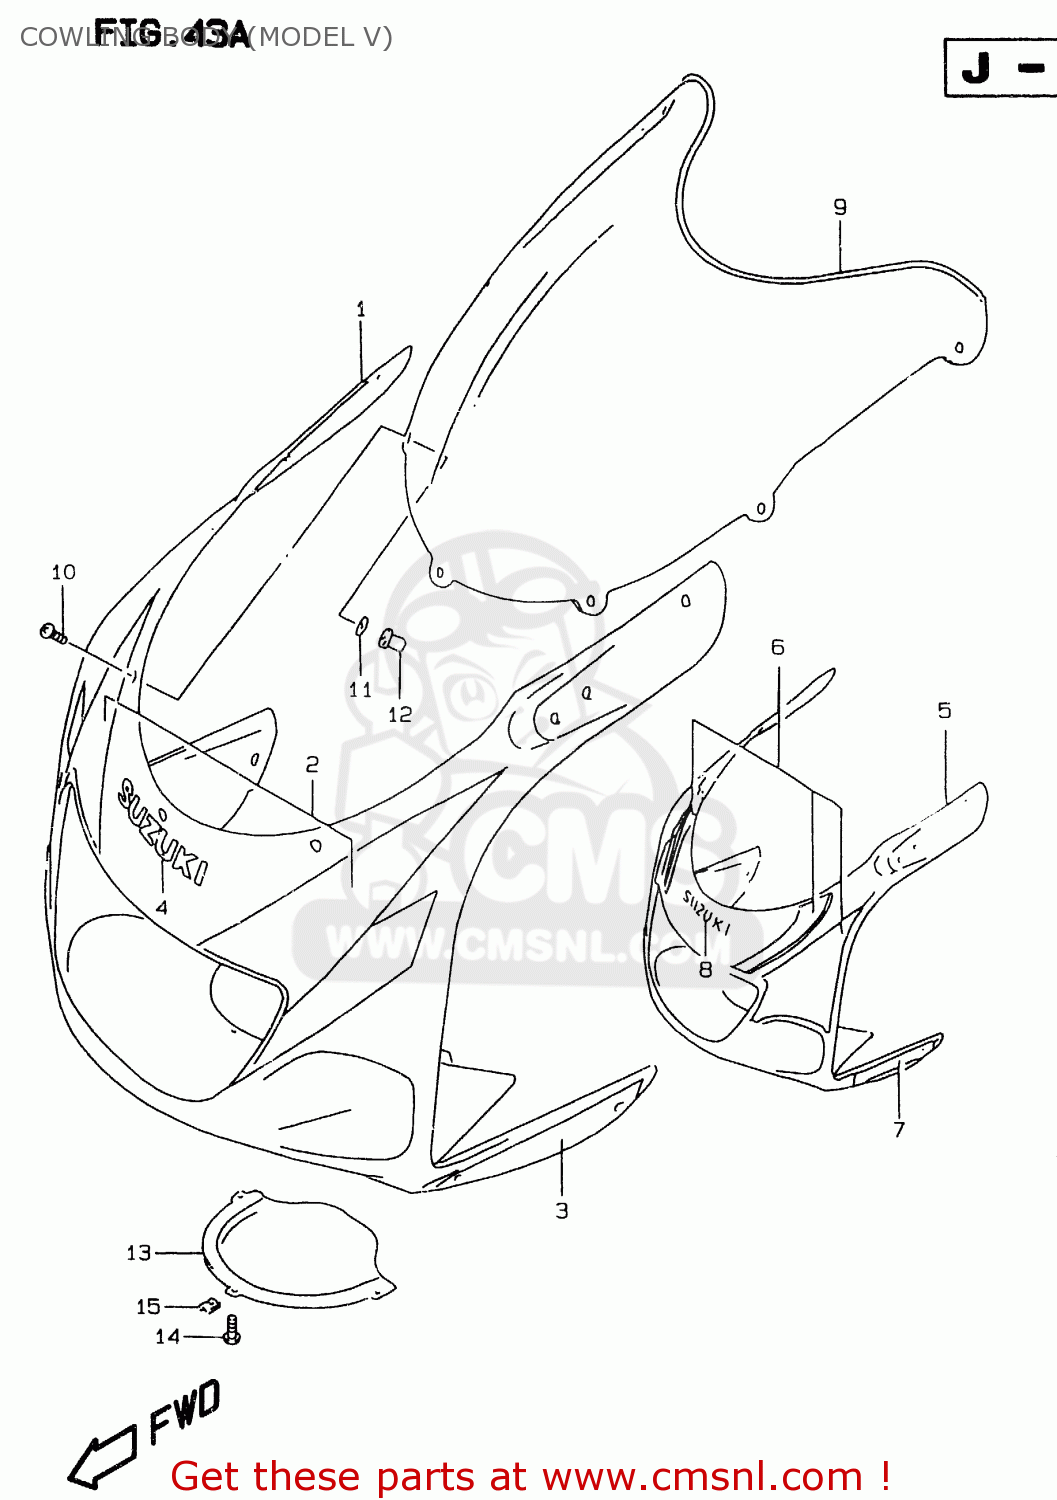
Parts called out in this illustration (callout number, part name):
1	COWLING ASSY,BODY
2	TAPE SET,COWL BODY FR
3	TAPE SET,COWL BODY SIDE
4	EMBLEM,SUZUKI
5	COWLING ASSY,BODY
6	TAPE SET,COWL BODY FR
7	TAPE SET,COWLING BODY SIDE
8	EMBLEM,SUZUKI
9	WINDSCREEN
10	SCREW(5X14)
11	WASHER
12	NUT
13	LID,BODY COWLING,LOWER
14	SCREW
15	NUT
